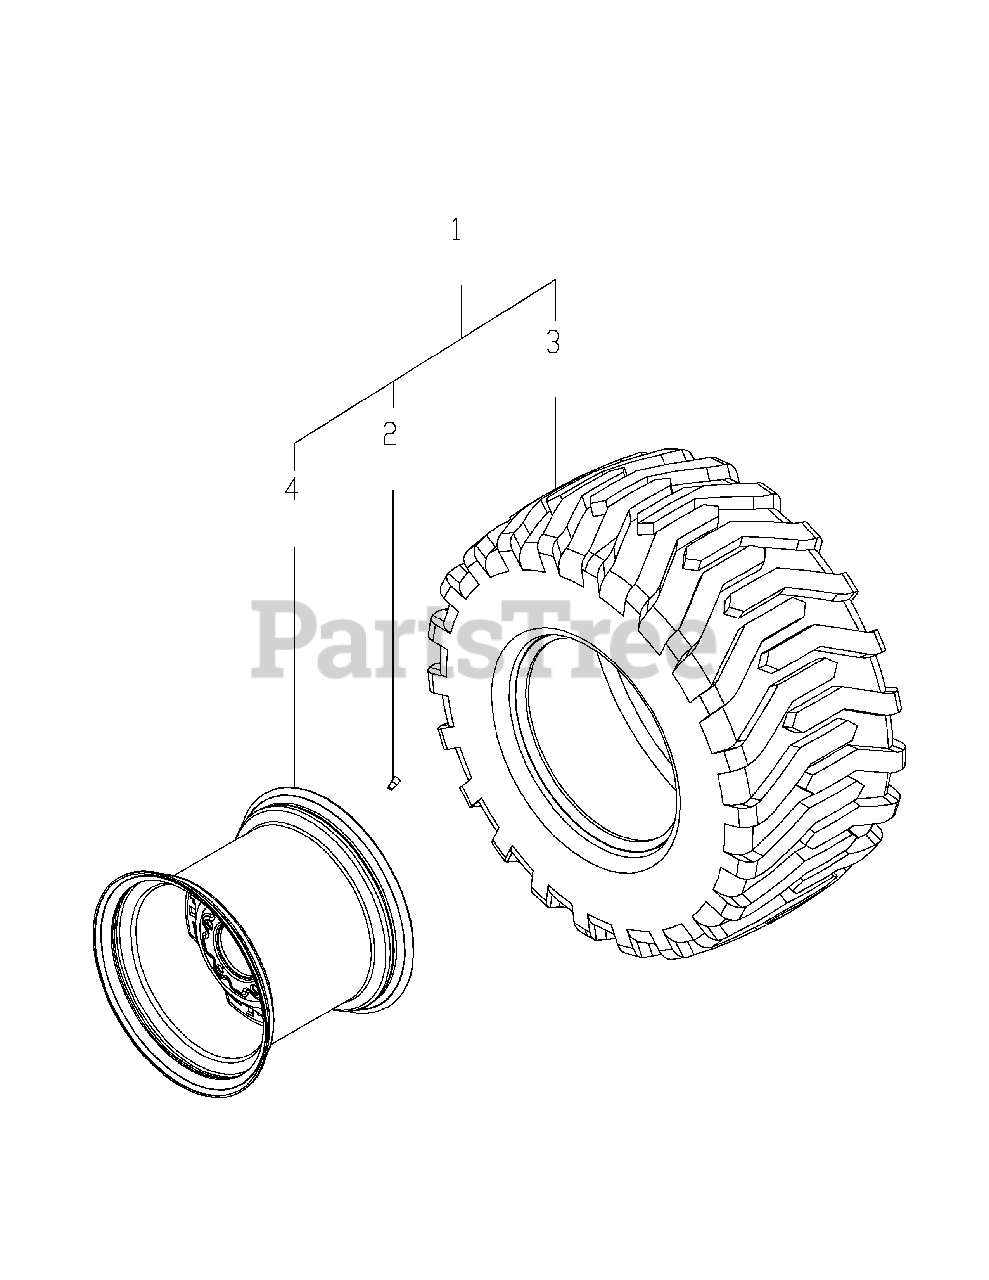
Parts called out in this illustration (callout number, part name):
1	TIRE ASM-REAR IND LH R4
1	TIRE ASM-REAR IND RH R4
3	TIRE,26X12-12 R4
